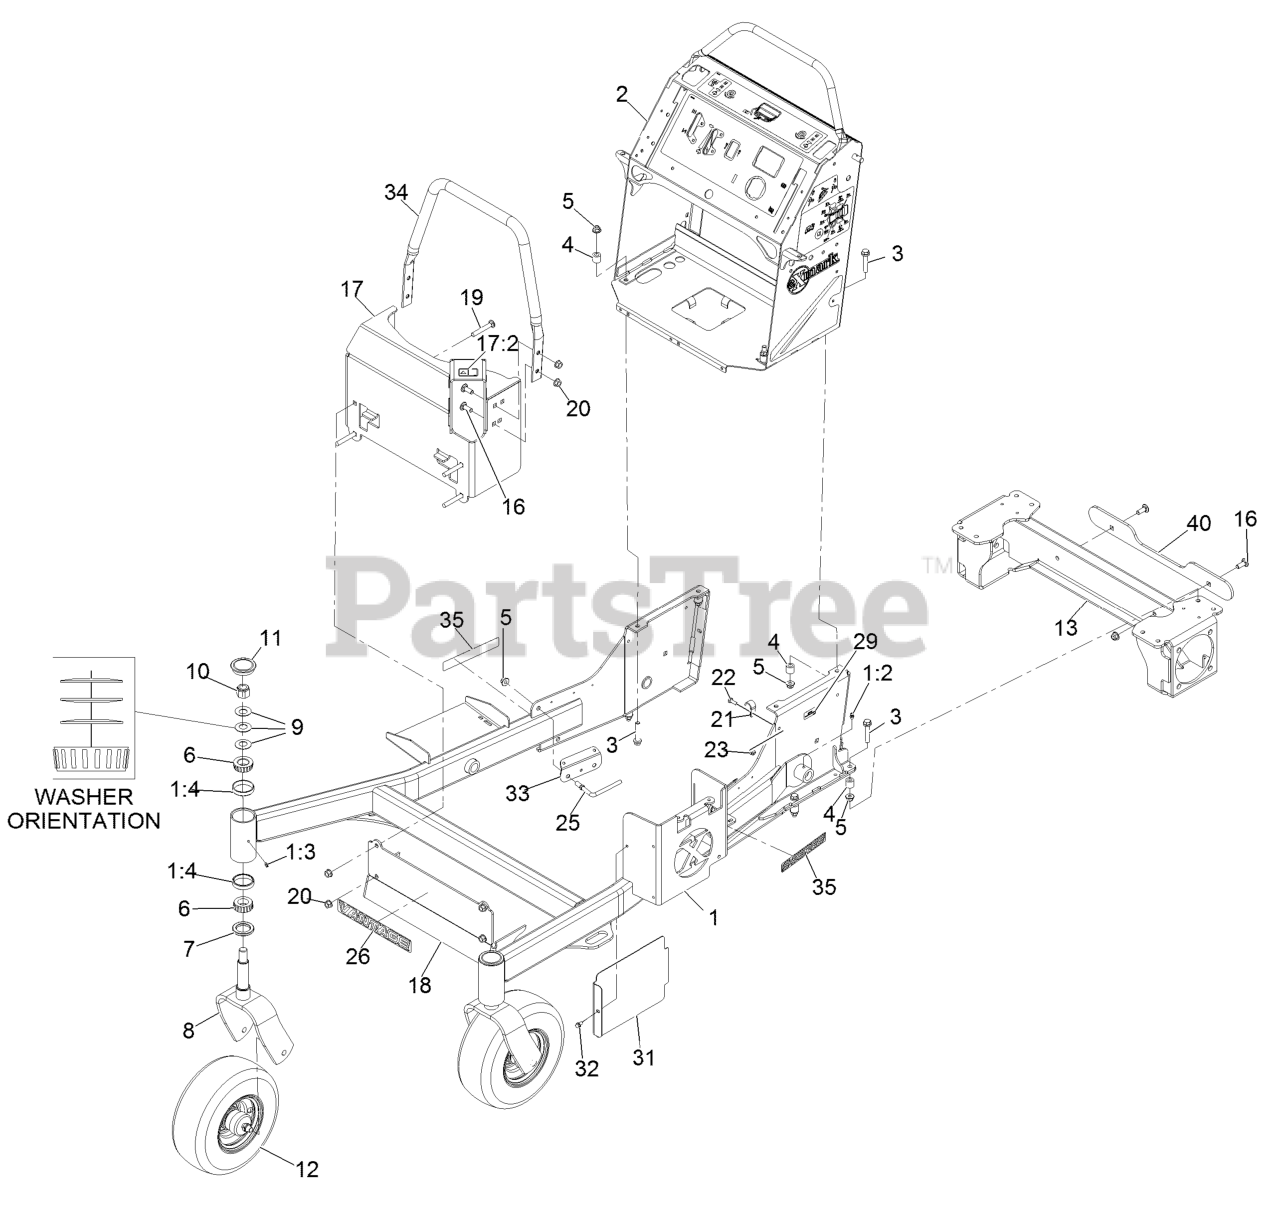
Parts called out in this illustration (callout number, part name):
1	FRONT FRAME ASM
1:2	FITTING-GREASE
1:4	CUP-BEARING
2	CONTROL TOWER ASM-EFI
3	SCREW-HHF
5	NUT-HF, NI
6	Cone-Bearing Tapered Roller
7	SEAL-GREASE
8	FORK-CASTER
9	WASHER-BELLVILLE
10	NUT-LOCK, NI
11	CAP-GREASE
12	WHEEL/TIRE AND BEARING AS
13	WELD, MOTOR FRAME
16	SCREW-CARR
17	ASM, MUFFLER GUARD W/ DEC
17:2	DECAL-WARNING
18	PANEL-GUARD
19	SCREW-CARR
21	CLAMP-CABLE
22	SCREW-HH
25	GUIDE-HOSE, SUPPORT
26	DECAL-VANTAGE LOGO
29	Decal-Patent Ttco.Com
31	SHIELD-HEAT, TALL
32	SCREW-HWH
33	GUARD-HOSE
34	TUBE-GUARD
35	DECAL-S-SERIES
40	PLATE, BUMPER SPACER
